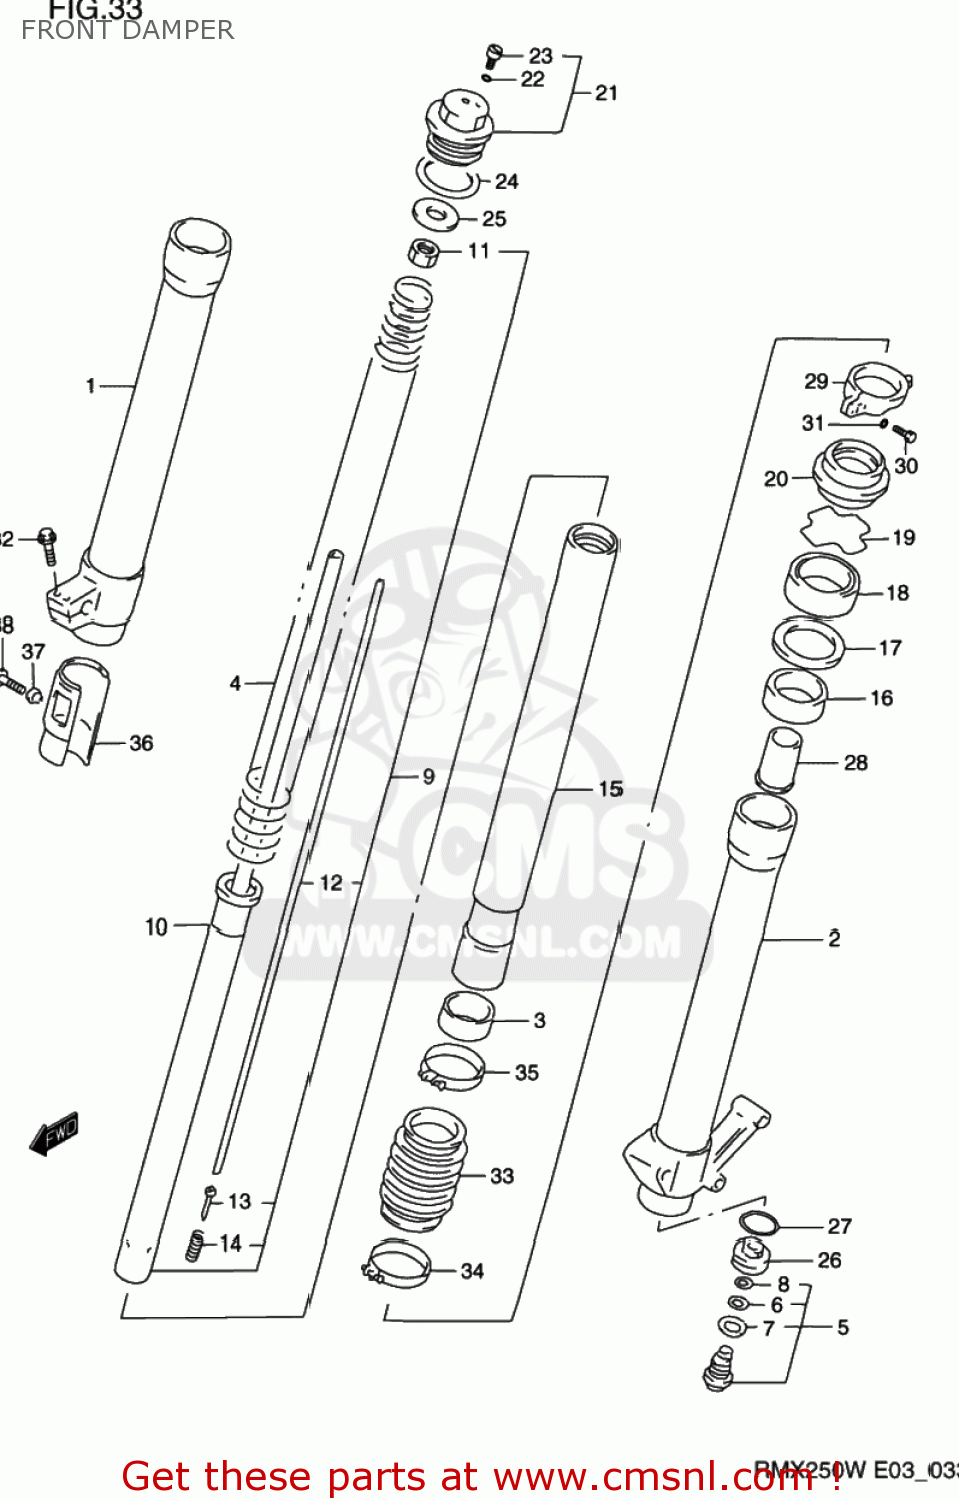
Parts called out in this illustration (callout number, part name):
1	TUBE,OUTER,RIGHT
2	TUBE,OUTER,LEFT
3	BUSH,SLIDE
4	SPRING,FR
5	BOLT,CTR
6	O RING,CTR BOLT
7	GASKET (NAS)
8	O RING,CTR BOLT UPR
9	DAMPER,FRONT
10	BUSH,SLIDE
11	NUT
12	ROD,PUSH
13	NEEDLE
14	SPRING,PUSH ROD
15	TUBE,INNER
16	BUSH,GUIDE
17	SPACER,SEAL
18	SEAL,OIL
19	RING,OIL SEAL STOPPER
20	SEAL,DUST
21	BOLT,FORK
22	O RING,PLUG
23	BOLT,PLUG
24	O RING
25	JOINT,SPRING
26	PLATE,END
27	O RING,FORK BOLT
28	PIECE,OIL LOCK
29	HOLDER
30	BOLT
31	WASHER (5.3X10X1.0)
32	BOLT
33	BOOT
34	CLAMP
35	BAND,BOOT
36	PROTECTOR,OUTER TUBE,RIGHT
37	WASHER
38	BOLT
